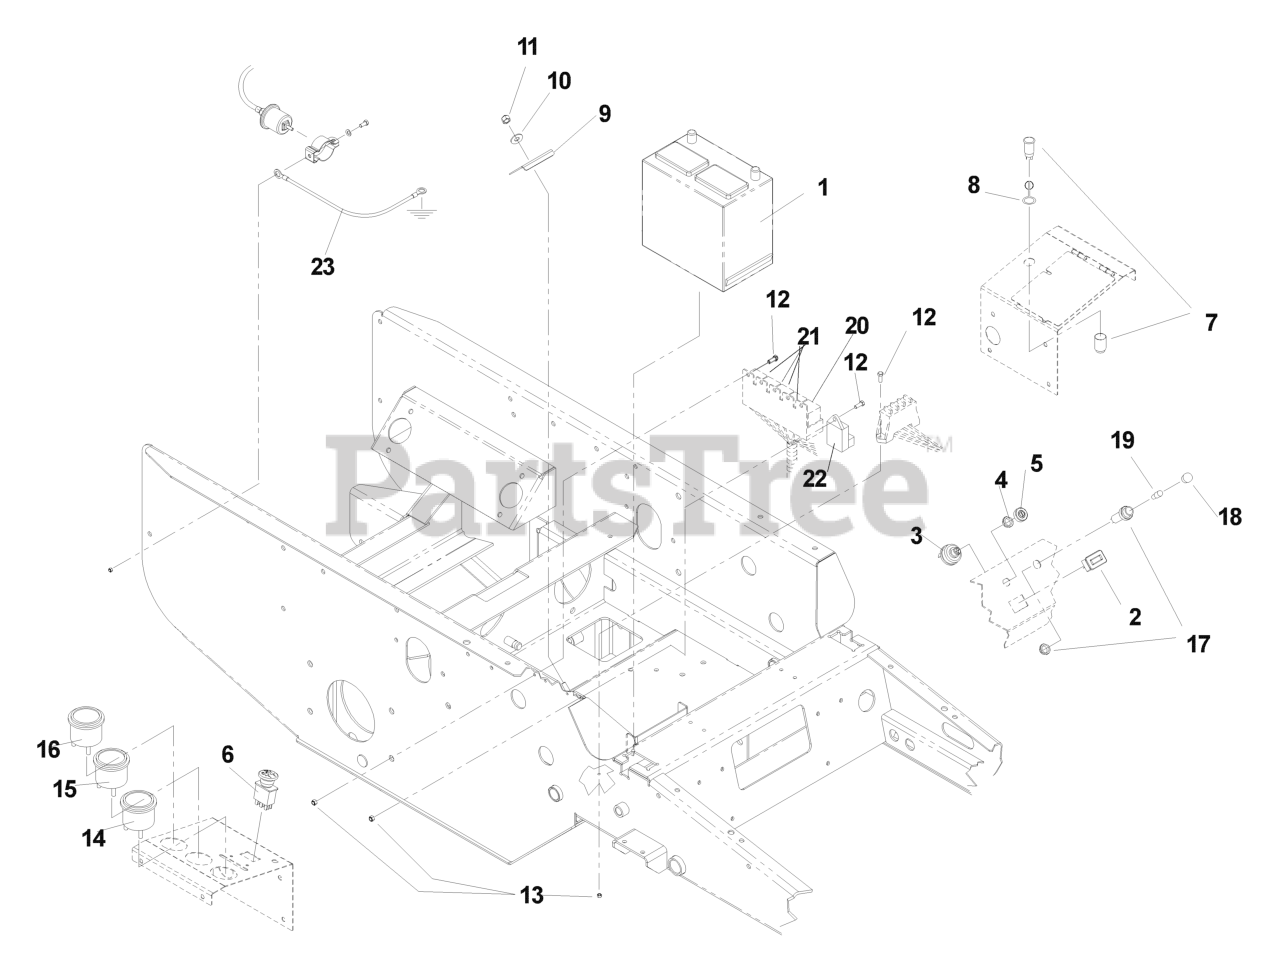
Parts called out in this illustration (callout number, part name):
2	DIGITAL HOUR METER
3	IGNITION SWITCH KIT
4	DNO IGNITION NUT
5	CAP IGNITION NUT
6	RP.SWITCH, BLADE
7	POWER SOURCING HSG
8	POWER SOURCE CAP
10	WASHER 5/16 FLAT
11	NUT 5/16 NYLOC
12	SCREW 10-24 X 3/4
13	NUT 10-24 NYLOC
14	TEMP GAUGE DATCON #100182
15	GAUGE, AMPMETER DATCON 100160
16	GAUGE, OIL PRES DATCON 100172
17	LAMP SPROCKET
22	TIMER/GLOW PLUG
